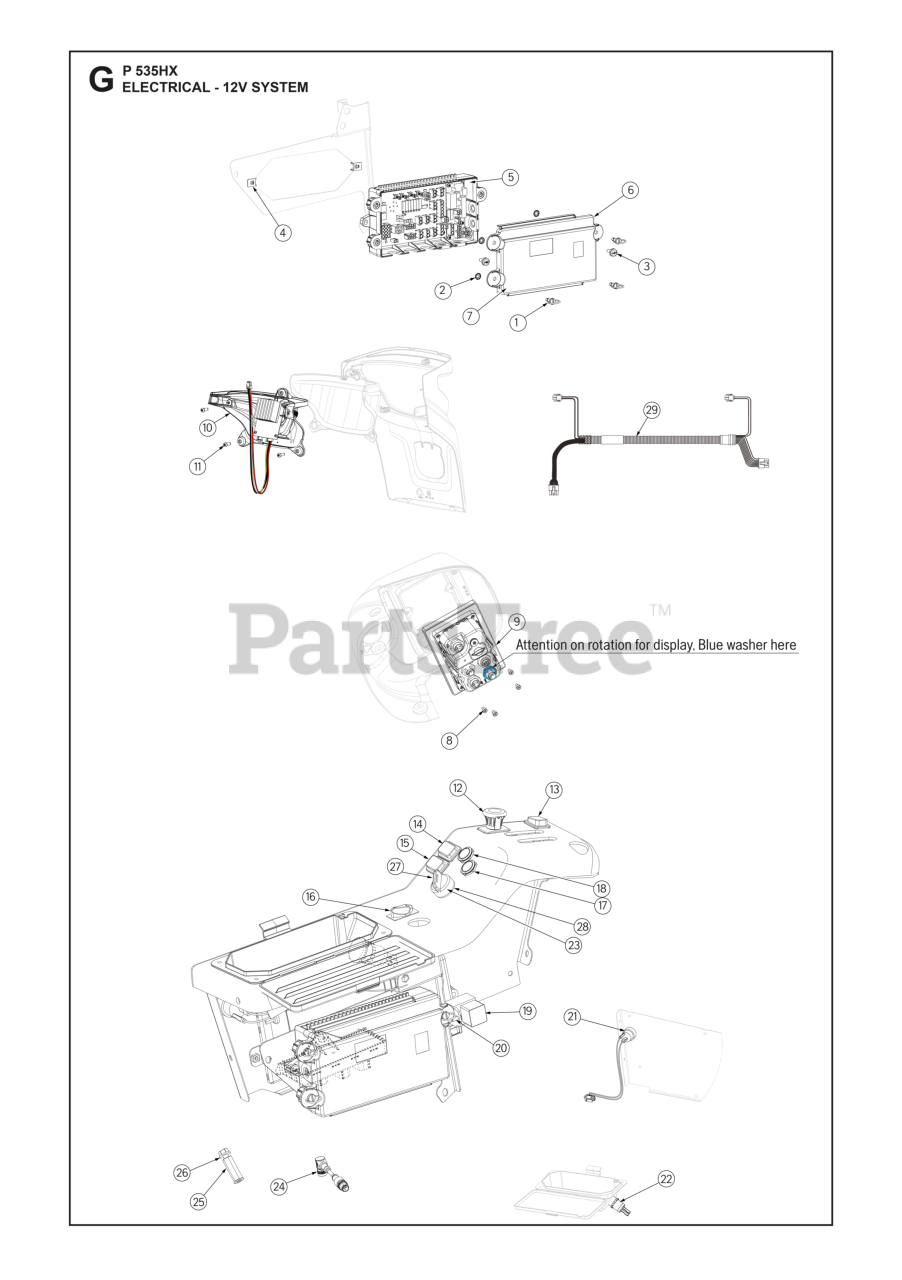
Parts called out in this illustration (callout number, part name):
11	SCREW ITXPANT T50X16 ZN/FE (A
12	SWITCH.PTO.10AMP.SEALED.6P.SPS
26	SCREW EHHFM
